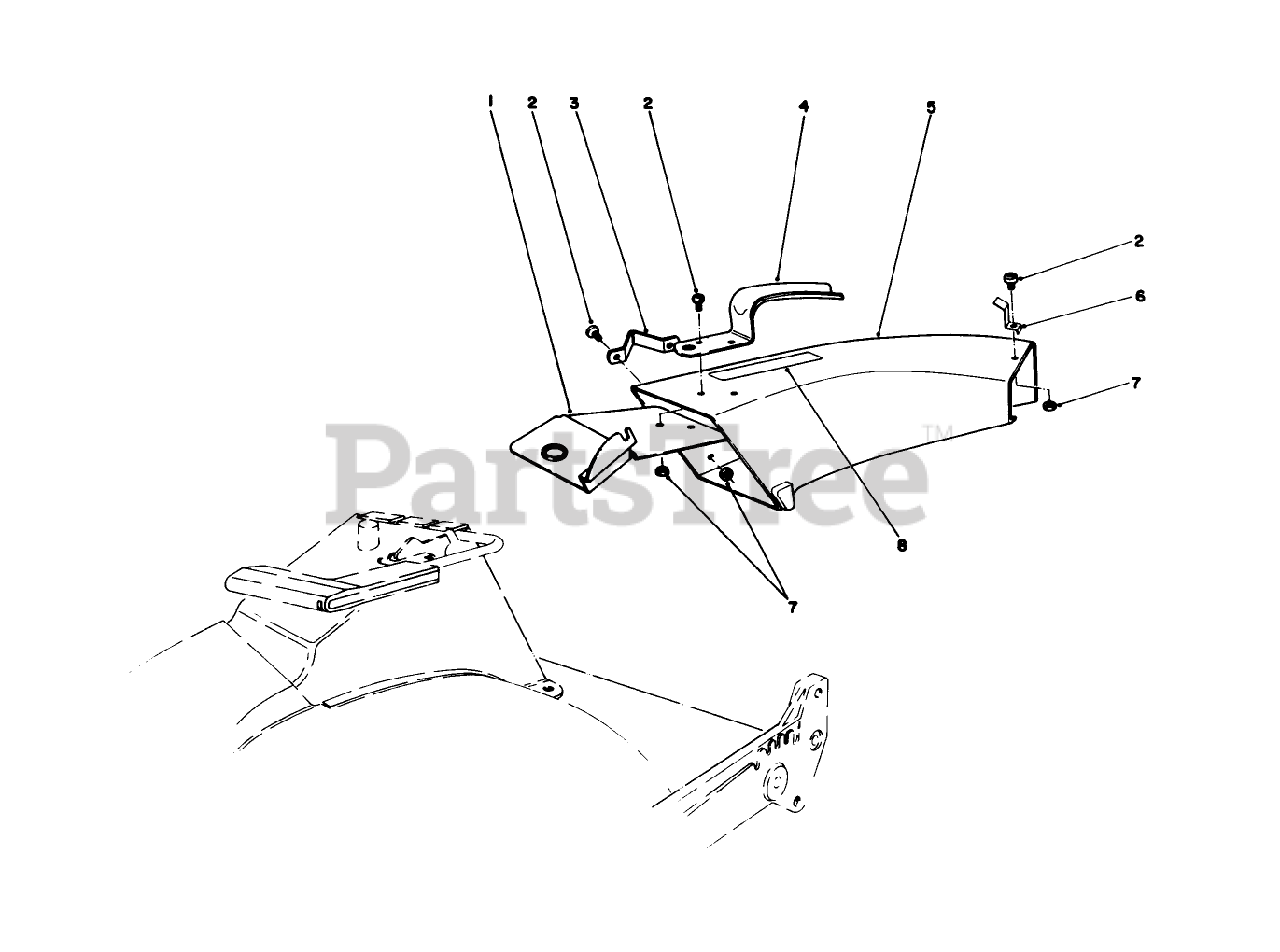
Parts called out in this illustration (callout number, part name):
2	10-24 X 5/8 PAN HD MS
4	CHUTE HANDLE
5	ORDER 59168 W.G.#
7	NUT-LOCK, NI
